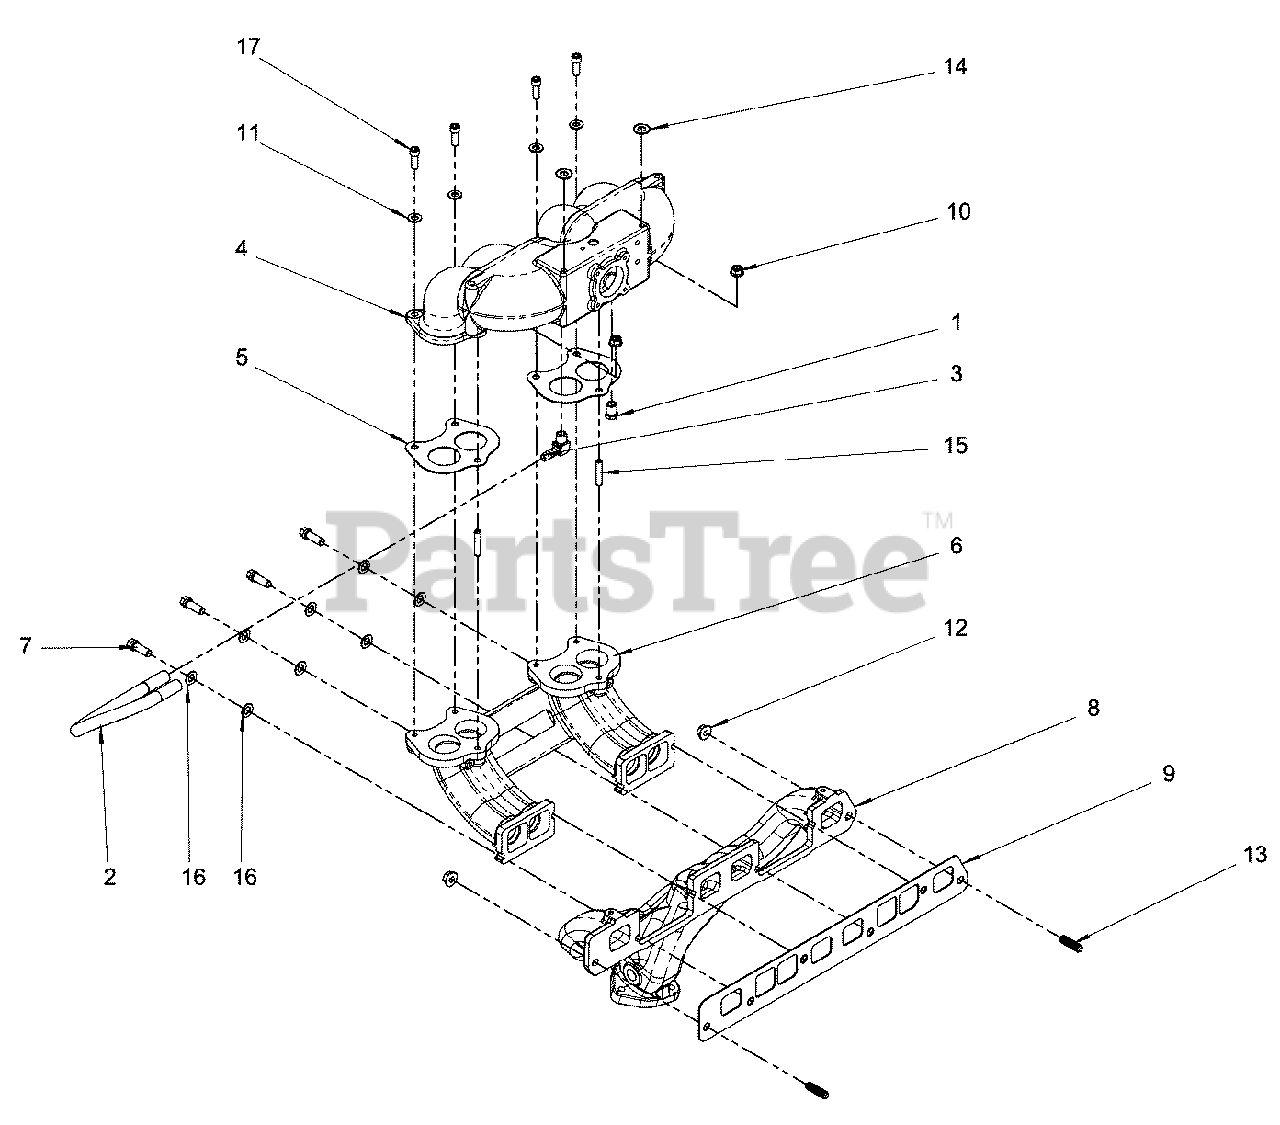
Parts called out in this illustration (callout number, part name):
1	* PLUG
2	* FUEL HOSE
3	* FITTING
4	* UPPER INTAKE MANIFOLD
5	MANIFOLD GASKET
6	* LOWER INTAKE MANIFOLD
7	* BOLT
8	* EXHAUST MANIFOLD
10	* NUT
11	* WASHER
12	* NUT
13	* STUD
14	* WASHER
15	* STUD
16	* WASHER
17	* BOLT
